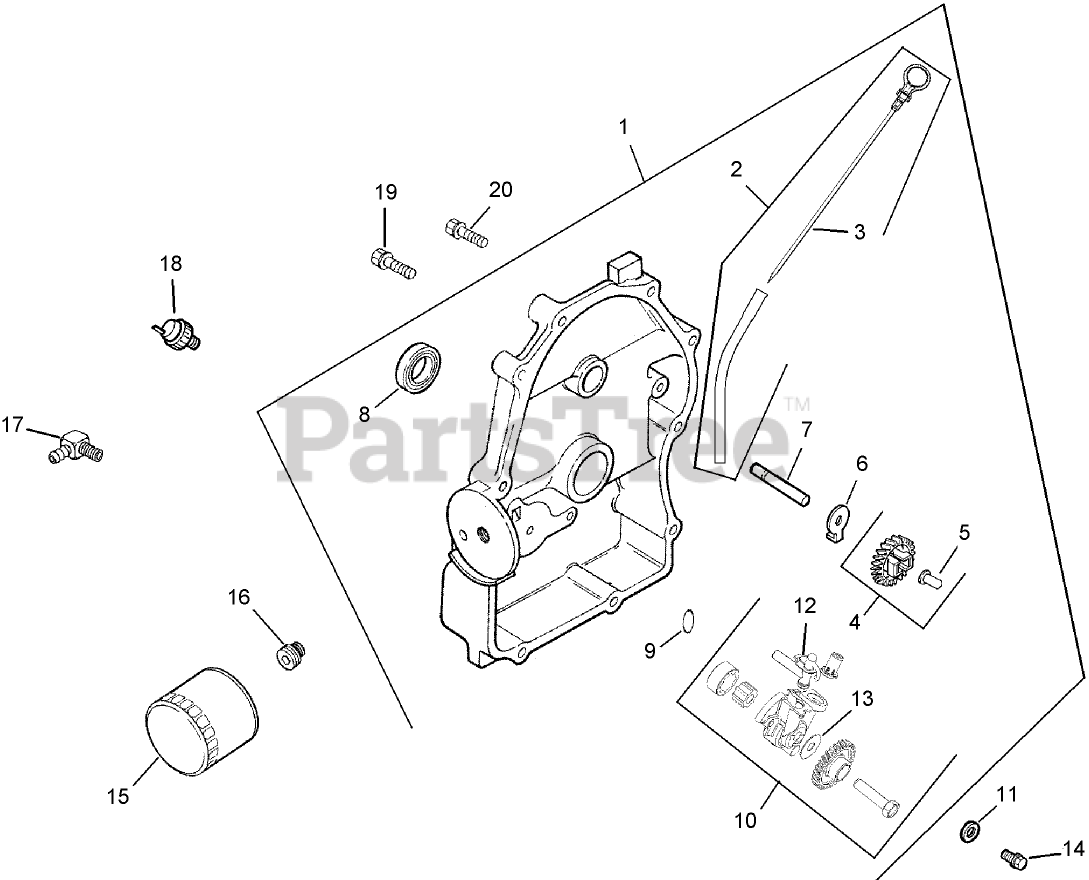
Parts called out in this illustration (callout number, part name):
1	Kit, closure plate (Includes 2-12)
2	Kit, dipstick and tube (Includes 3)
3	Dipstick
4	Kit, governor gear w/pin (Includes 5)
5	PIN-REGULATING, GOVERNOR
6	Tab-Locking
7	SHAFT-GEAR, GOVERNOR
8	SEAL-OIL (P-T-O END)
9	O-Ring
10	Oil pump Assembly (Includes 11 and 12)
11	O-RING
12	TUBE-PICK UP, OIL
13	WASHER-FLAT (6 MM)
14	SCREW-FLANGE, THREAD FORMING (M6X1.0X25)
15	Filter-Oil
16	Nipple-Filter, Oil
17	Connector-Hose, 90 Deg
18	SWITCH-PRESSURE, OIL
19	Screw-HF (M8x1.25x45)
20	SCREW-FLANGE (M8X1.25X45)
